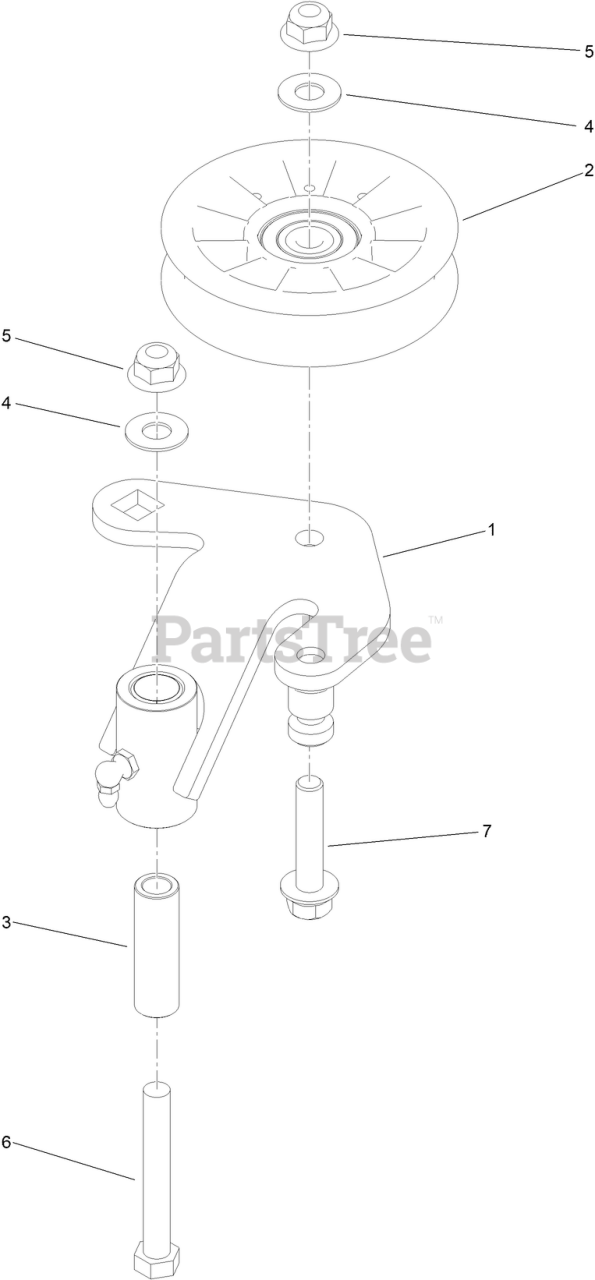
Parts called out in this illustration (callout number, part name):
1	ARM-IDLER
2	PULLEY-FLAT IDLER
3	PIVOT-IDLER
4	WASHER,FLAT,3/8ST/ST 18-8
5	Nut-Hex Flange
6	HHCS,3/8-16X2-3/4,1TL,ST/ST 18-8
7	SCREW-HHF
